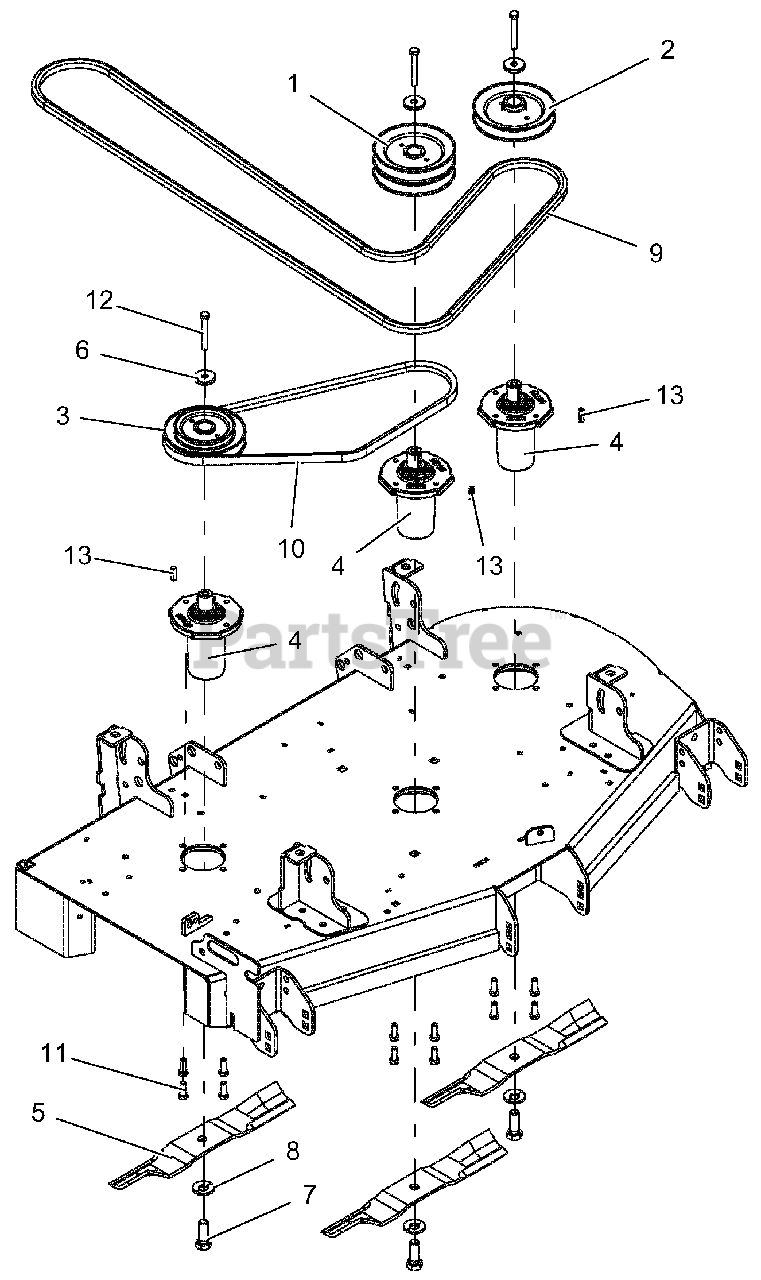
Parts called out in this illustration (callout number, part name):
1	PULLEY, DOUBLE-1" ID X 5.75" OD-BLACK
2	PULLEY, V - 1" ID X 5.75" OD-BLACK
3	PULLEY, DOUBLE -1" ID X 5.75" & 4.25" OD
4	SERVICE, ASM SPINDLE- DUCTILE
5	BLADE, 16.19" MOWER (HI-LIFT)
6	RETAINER, SHEAVE SPINDLE
7	BLT, HEX .62-18X1.75 GR8 YWZC
8	WSHR, BLVL .63X1.625X.14
9	BELT, BB 118.00 WRAPPED HEX
10	V-Belt, B-Raw Edge Cogged
11	BLT-HEX .38-16X1.00 GR5 YWZC EP30
12	BLT-HEX .38-16X2.75 GR8 YWZC
13	KEY-SQ .250X.250X1.00 RC 40-50
